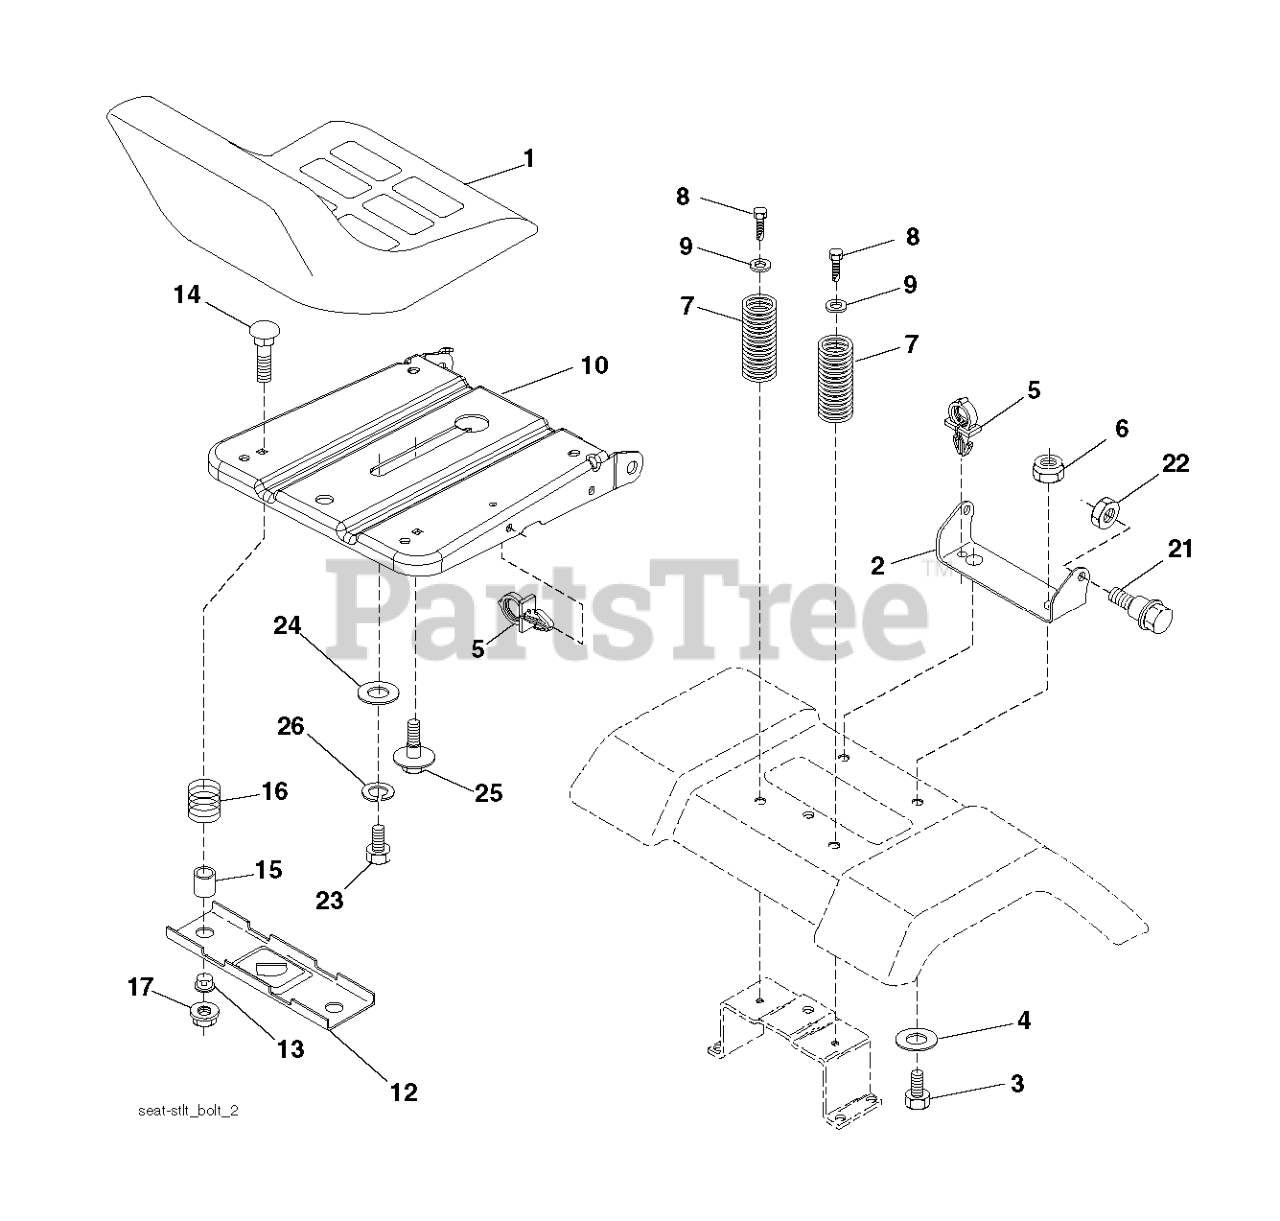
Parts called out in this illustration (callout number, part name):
1	CUTTING DECK RIDER
5	BLADE HOUSING ASSY
6	BEARING HOUSING
8	SPACING SLEEVE
10	BLADE HOUSING ASSY
11	BEARING HOUSING
13	SPACING SLEEVE
16	WASHER BRB 8.4X17
17	LOCKNUT M8
25	WASHER
27	BELT TENSIONER ASSY KIT
27	BELT TENSIONER ASSY
28	BELT TENSIONING ARM
31	BOLT
32	WASHER
32	WASHER SHOULDER ASSY
33	SCREW
34	LOCKNUT M8
